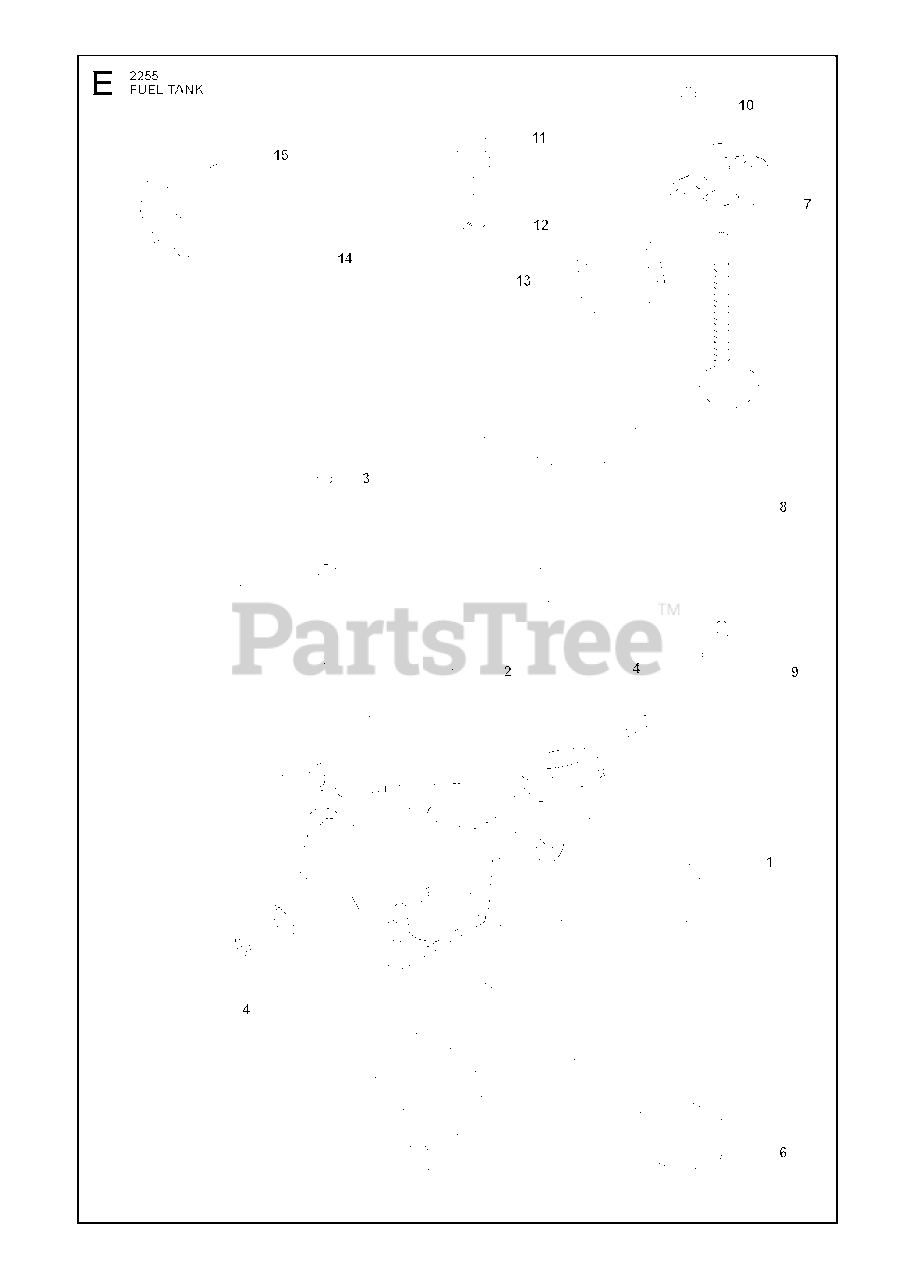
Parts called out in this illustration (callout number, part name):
3	SCREW IHSCFM
6	ANTIVIBE ELEMENT
8	FUEL HOSE
9	FUEL FILTER
11	AIR PURGE BUBBLE
12	HOSE CLAMP
15	SCREW IHSCFM
